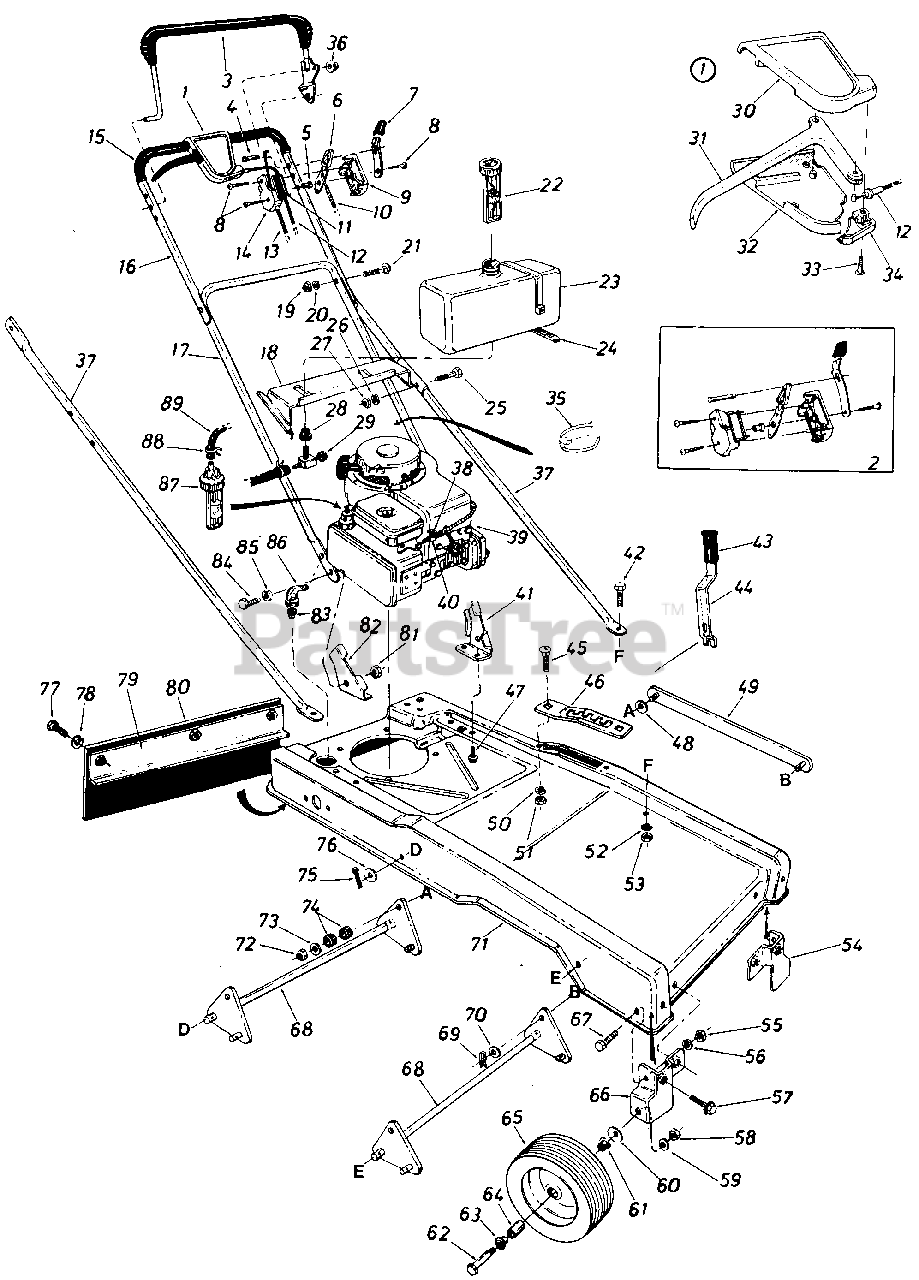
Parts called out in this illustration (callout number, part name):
1	KIT-CLUTCH CONTROL
2	KIT-THROTTLE CONTROL
4	PIN-LOCKING
5	PIN-CONTROL DISC
6	LEVER-THROTTLE CONT-REV
7	KNOB
8	SCREW-TRUSS MACH
9	PANEL HALF-CONTROL
10	WIRE-CONTROL
11	LABEL
12	CABLE-CLUTCH
13	CABLE-CLUTCH
14	PANEL HALF-CLUTCH
15	GRIP-SHRINK-25 IN
16	HANDLE-UPPER-CHROME
17	HANDLE-LOWER PAINTED
18	BRACKET-GAS TANK MTG
19	NUT-HEX 5/16-18
20	WASHER-LOCK-5/16
21	BOLT-CARRIAGE 5/16-18 X 1.50
22	GAUGE-GAS
24	TIE-CABLE
25	SCREW-HEX 5/16-24 X 1.25
26	WASHER-LOCK-5/16
27	NUT-5/16-24
28	BUSHING
29	VALVE-SHUT OFF
30	COVER-HALF-CONTROL
31	LEVER-CONTROL
32	COVER-HALF CONT-LWR
33	SCREW-FL C-SUNK AB
34	CAP-CABLE MTG
35	TIE-CABLE
37	STRUT-43.44 IN LG
38	SCREW-HEX WASH HD TAP
40	CLAMP-CASING
41	BRACKET-HANDLE MTG
42	SCREW-HEX 5/16-18 X .75
43	GRIP-FL BAR-END
44	HANDLE-LIFT
45	BOLT-CARRIAGE 5/16-18 X .62
46	BRACKET-SUPPORT
47	SCREW-HEX WASH HD 5/16-18X1/2
48	WASHER-FL-.406ID 1.25OD X.157/.172
49	LINK ASSY
50	WASHER-LOCK-5/16
51	NUT-HEX 5/16-18
52	WASHER-LOCK-5/16
53	NUT-HEX 5/16-18
54	BRACKET ASSY-WHL-LH
55	NUT-HEX 5/16-18
56	WASHER-LOCK-5/16
57	SCREW-HEX SEMS 5/16-18 X .75
58	NUT-HEX CENTER L-3/8-16
59	WASHER-LOCK-3/8
60	WASHER-BELL .400 ID X .88 X .060
61	BEARING-BALL
62	SCREW-HEX 3/8-16 X 2.00
63	BEARING-FLANGE
65	WHEEL ASSY W/TIRE-8 X 1.75 WAFFLE
66	BRACKET ASSY-WHL-RH
67	SCREW-HEX SEMS 5/16-18 X .75
68	SHAFT ASSY-LIFT BRKT
69	PIN-INTERN COT-5/16 DIA
70	WASHER-FL-.385 ID X .87 OD X .06
71	FRAME-HI WHEEL
72	NUT-HEX INS L-3/8-24
73	WASHER-FL-.385 ID X .87 OD X .06
74	WASHER-RUBBER
75	PIN-COTTER-1/8 DIA X 1.00
76	WASHER-FL .510 X .995 X .060
77	SCREW-HEX 1/4-20 C .62
78	LOCK WASHER 1/4 DIA
79	STRIP ASSY RETAINING
81	NUT-HEX JAM 3/8-18
82	BRACKET-HANDLE MTG
84	SCREW-HEX 3/8-16 X .75
85	WASHER-LOCK-3/8
87	VALVE-FUEL CONTROL
88	CLAMP-HOSE
89	FUEL LINE-15IN
